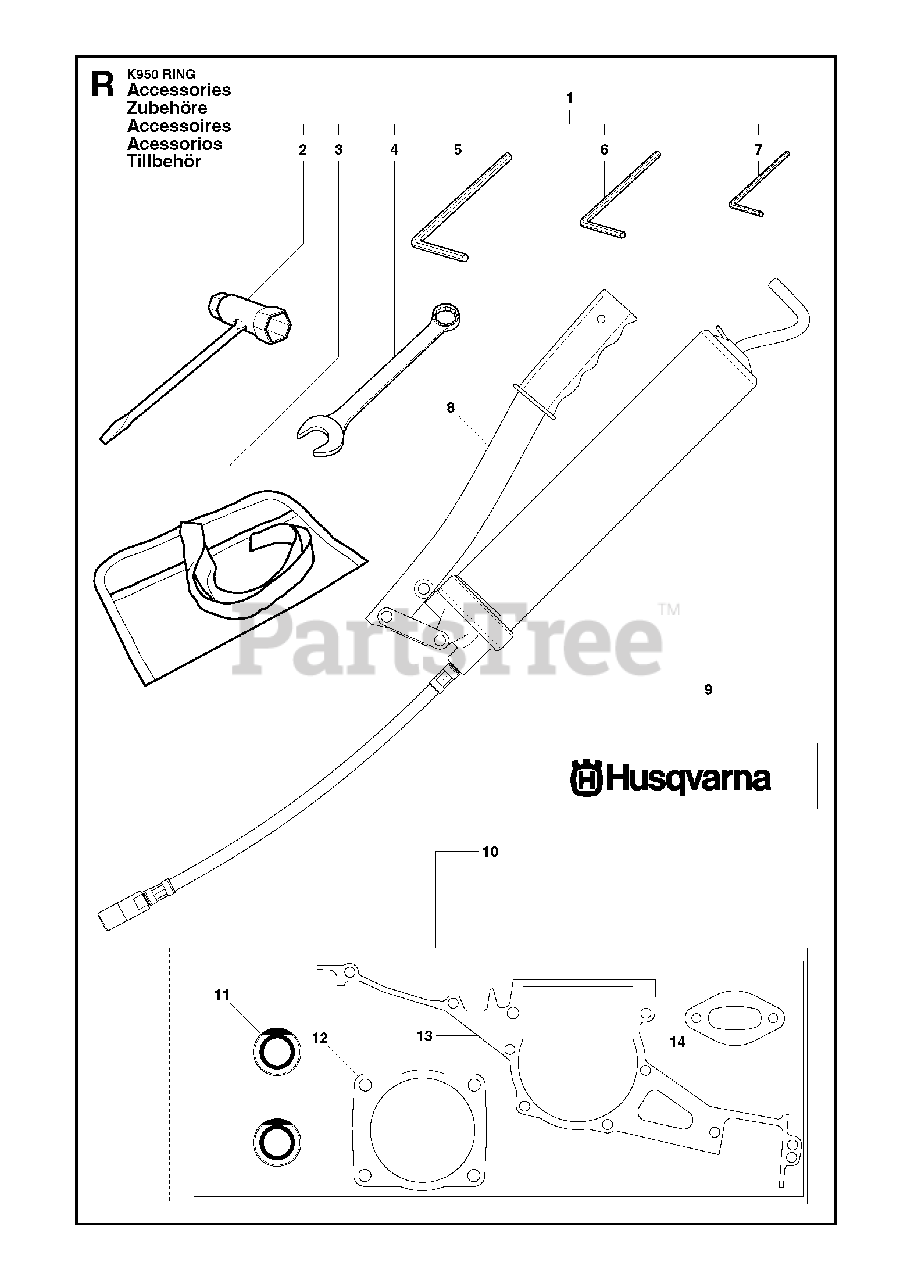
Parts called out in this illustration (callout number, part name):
2	COMBINATION WRENCH13-19mm
7	WRENCHAllenkey 4mm
9	GREASE
11	SEALING RING
12	CYLINDER BASE GASKET
14	GASKET
